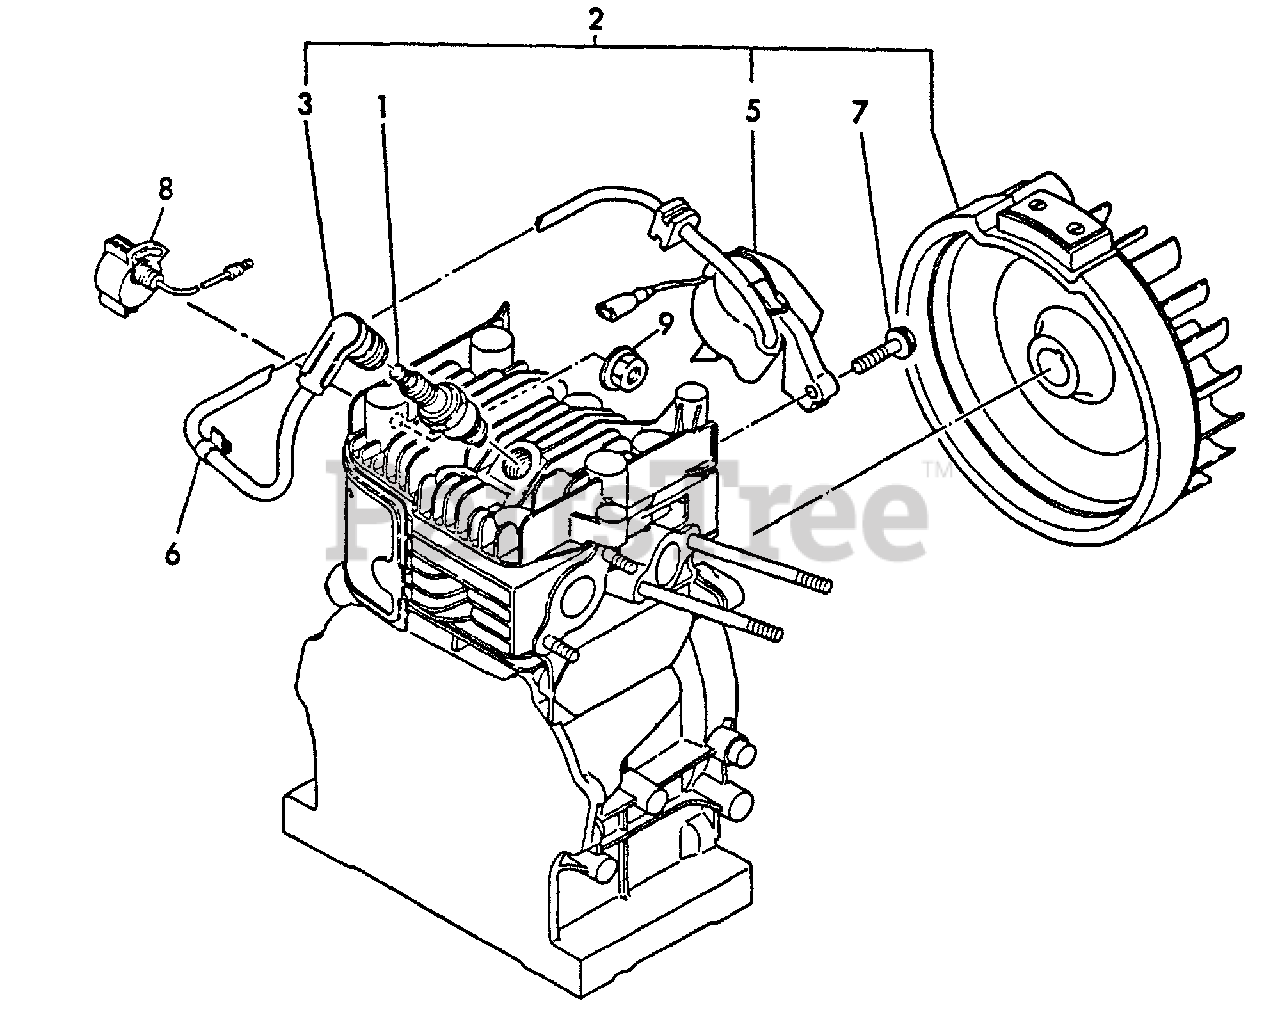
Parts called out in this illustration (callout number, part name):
1	SPARK PLUG
2	FLYWHEEL
3	CAP, PLUG
5	COIL, IGNITION
6	CLAMP
7	BOLT - 6×30
8	IGNITION SWITCH ASSY
9	U-NUT M8
